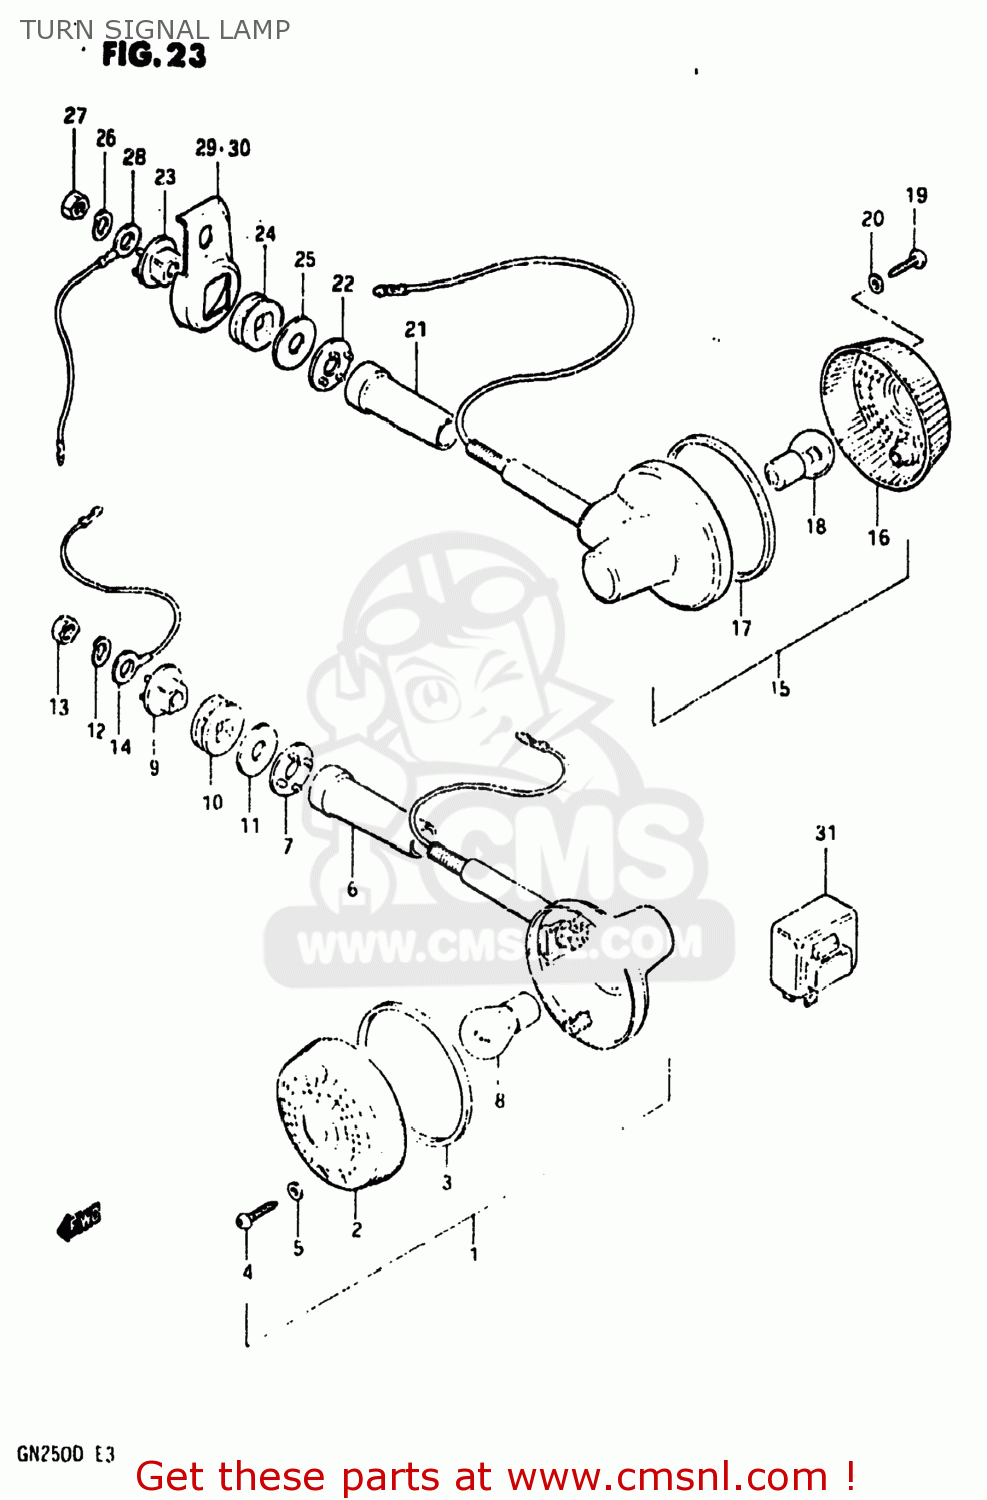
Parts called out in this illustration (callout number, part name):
1	LAMP ASSY,TURNSIGNAL
2	LENS
3	GASKET (NAS)
4	SCREW
5	GASKET (NAS)
6	COVER,STAY
7	SPACER
8	BULB(12V23W,STANLEY,A4577A)
9	SPACER
10	CUSHION
11	WASHER (10.5X30X2.3)
12	LOCK WASHER
13	NUT
14	LEAD WIRE,EARTH
15	LAMP ASSY,RR TURNSIGNAL
16	LENS
17	GASKET (NAS)
18	BULB(12V23W,STANLEY,A4577A)
19	SCREW
20	GASKET (NAS)
21	COVER
22	SPACER
23	SPACER
24	CUSHION
25	WASHER (10.5X30X2.3)
26	LOCK WASHER
27	NUT
28	LEAD WIRE,EARTH
29	BRACKET,RR TURNSIGNAL LAMP,R
30	BRACKET,RR TURNSIGNAL LAMP,L
31	RELAY,TURN SIGNAL
